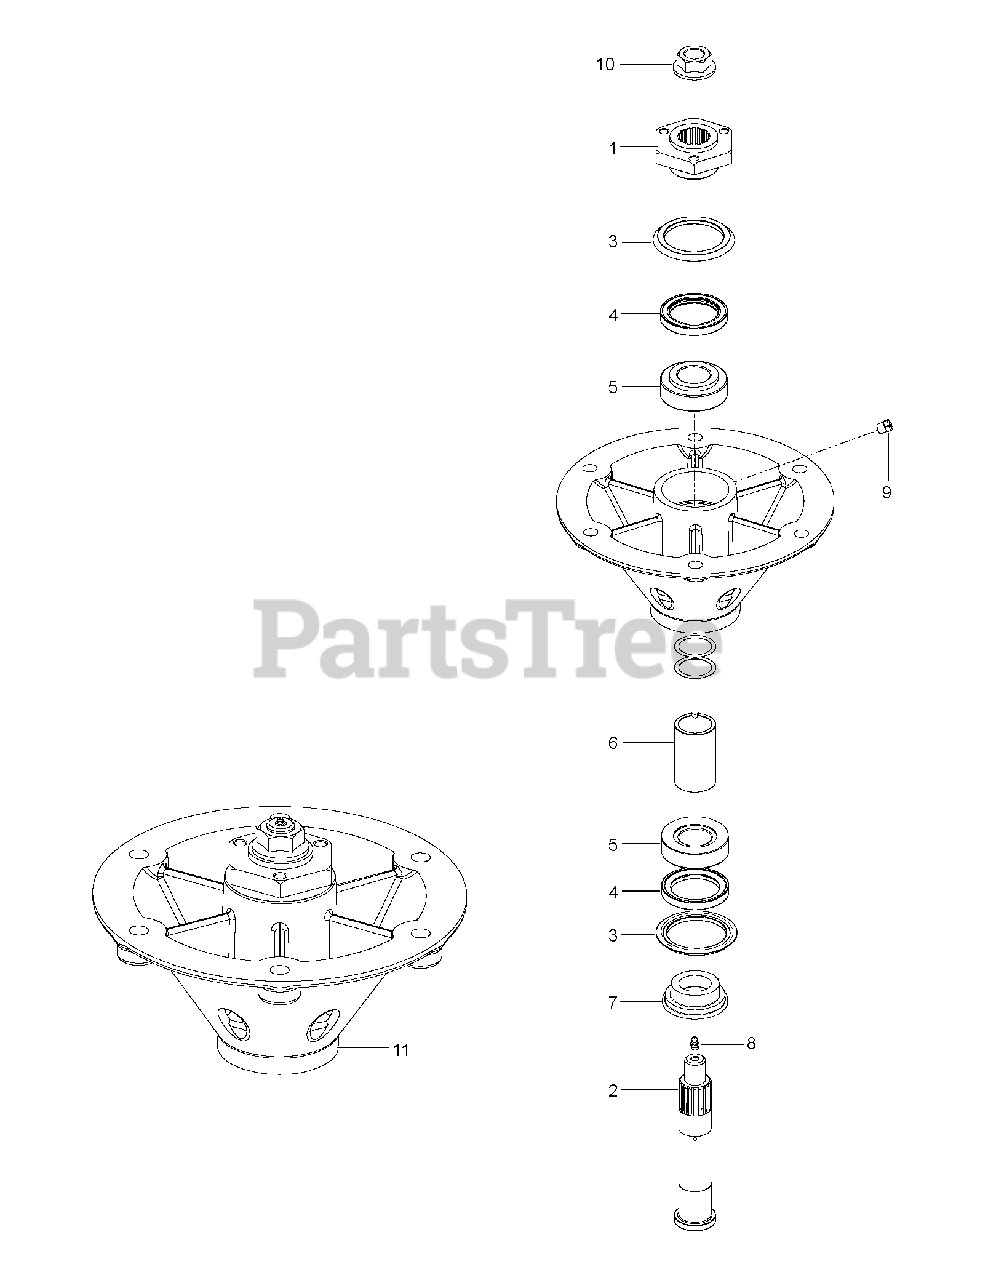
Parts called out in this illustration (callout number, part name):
3	SEAL V-RING 55MM
4	SEAL SHAFT
5	BEARING KIT
8	ZERK
9	PLUG-VENTED
10	NUT FLANGE 3/4-16
11	Spindle Assembly, Alumi
